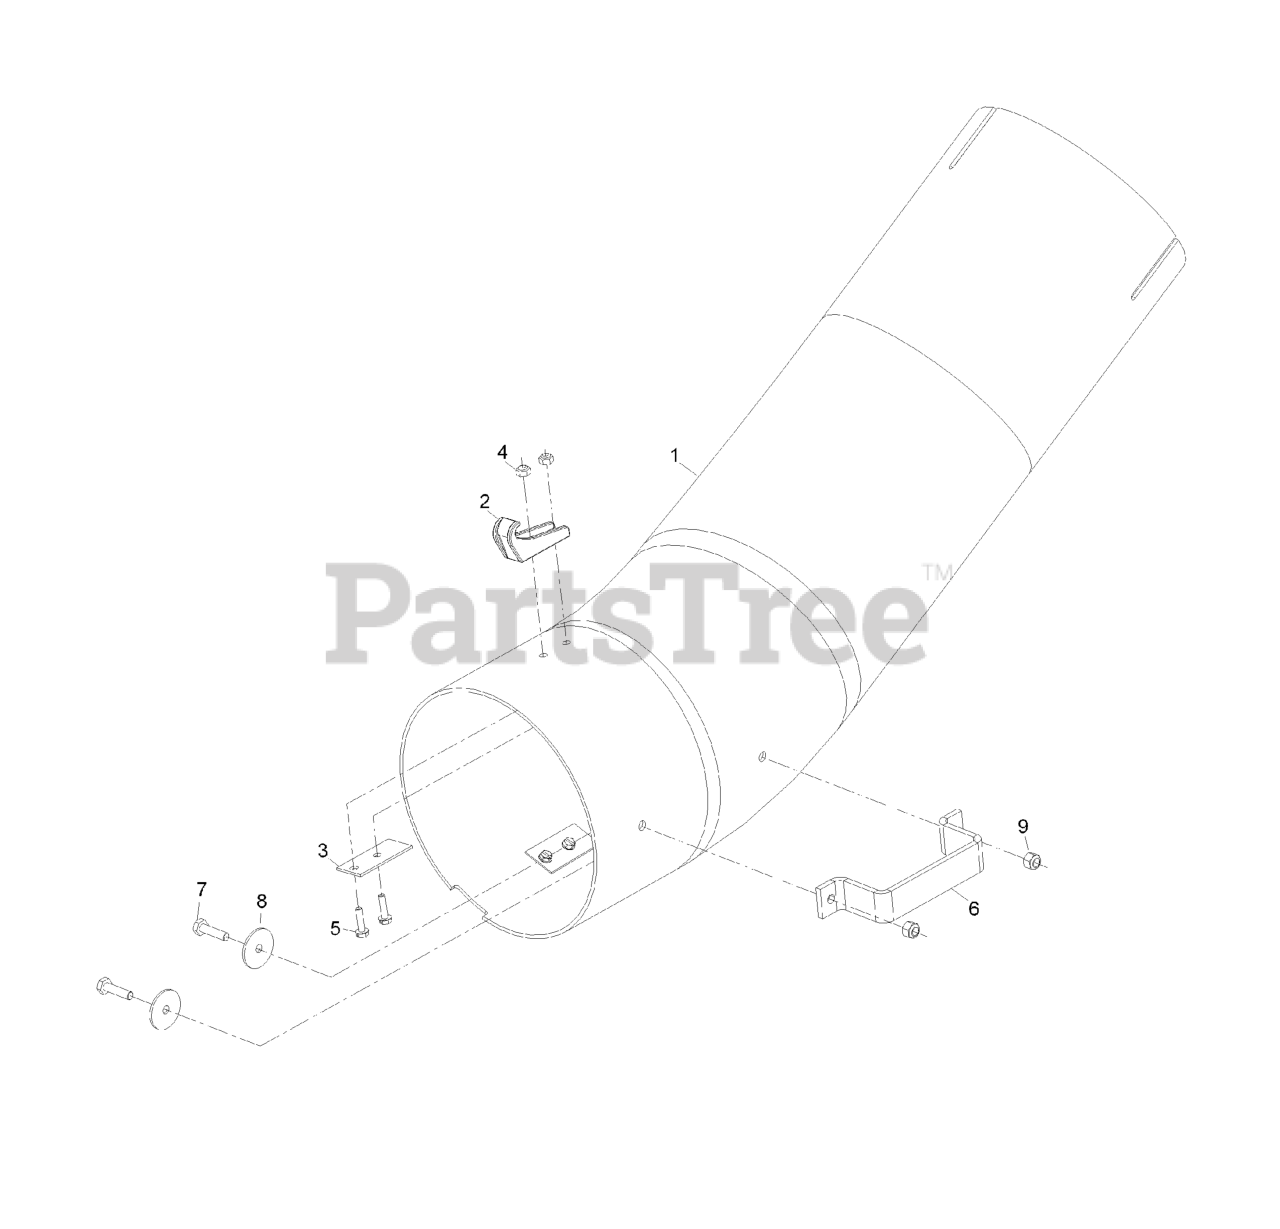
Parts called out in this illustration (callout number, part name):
2	LATCH-CATCH
3	PLATE-BACKING
4	TUBE-LOWER
5	SCREW-HH
6	WASHER-FLAT
7	NUT-LOCK, NI
8	NUT-LOCK, NI
9	SCREW-HWH
